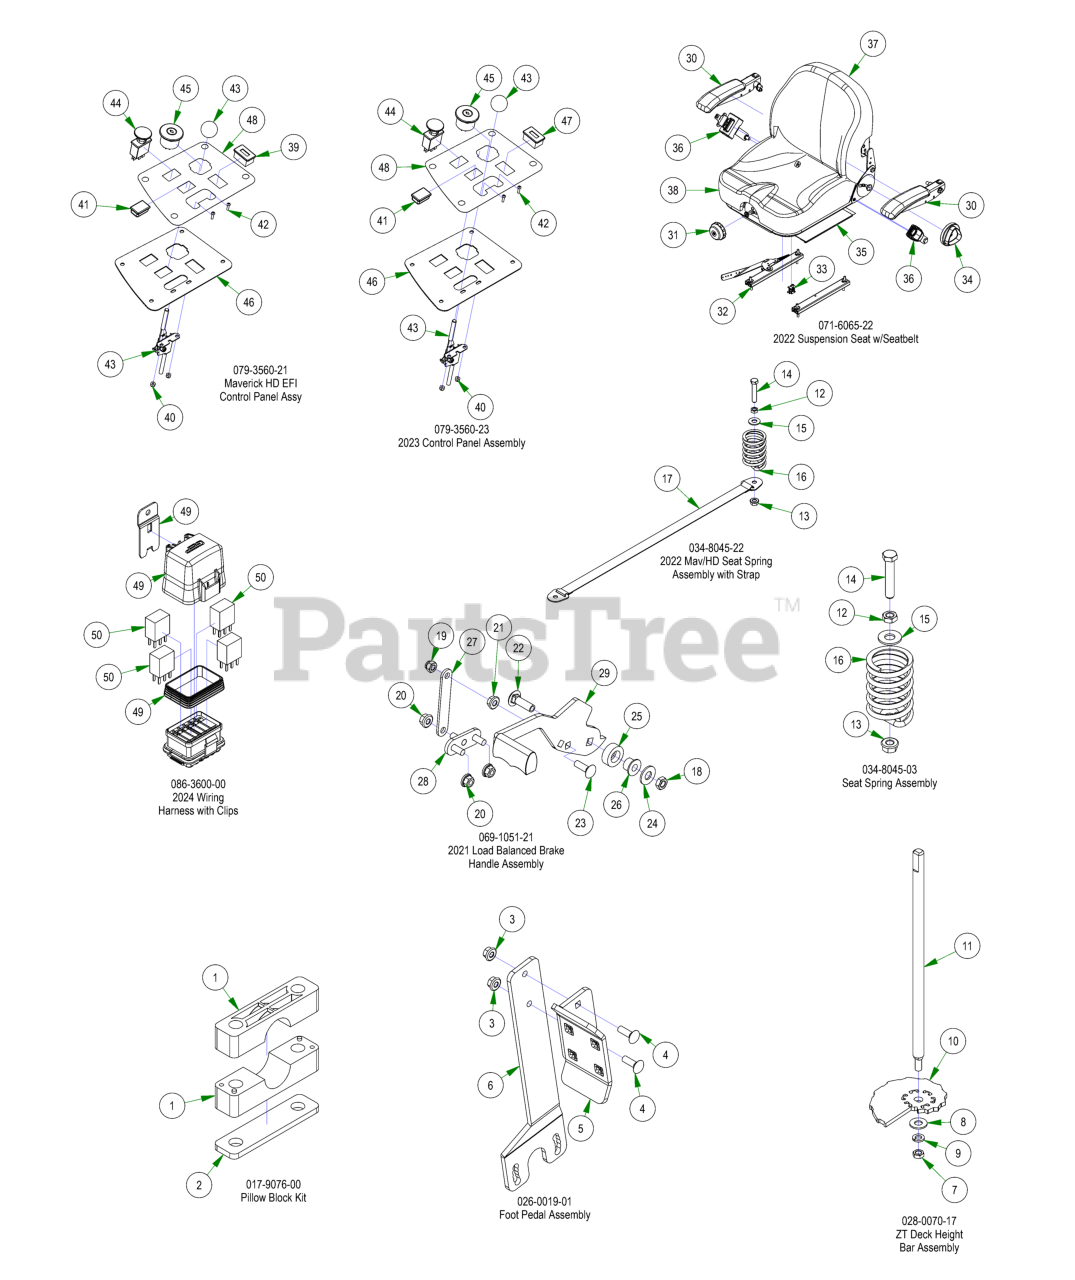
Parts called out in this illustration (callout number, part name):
1	Pillow Block MZ
2	Pillow Block Strap
3	5/16-18 NYLON INSERT FLANGE LOCKNUT ZINC
4	5/16-18 X 1 CARRIAGE BOLT (GR.8) ZINC
5	2017 MZ/ZT Shallow Foot Pedal
6	2017 MZ/ZT Deck Pedal Lever
7	3/8-24 HEX NUT ZINC YELLOW
8	3/8 FLAT WASHER USS (1" OD) ZINC
9	3/8 SPLIT LOCKWASHER ZINC
10	2017 MZ/ZT Cam Plate
11	2017 Deck Height Dial Rod ZT
12	3/8-16 Half Jam Nut
13	3/8-16 HEX SERRATED FLANGE NUT HARD/ZINC
14	3/8-16 X 2 HEX CAP SCREW (GR.5) ZINC
15	3/8 FLAT WASHER USS (1" OD) ZINC
16	Seat Spring
17	Seat Strap with Buckles
18	3/8-16 HEX JAM 2-WAY REVERSIBLE CENTER LOCKNUT ZINC
19	5/16-18 NYLON INSERT CAP LOCKNUT ZINC (BLK CAP)
20	5/16-18 NYLON INSERT FLANGE LOCKNUT ZINC
21	5/16-18 HEX SERRATED FLANGE NUT HARD/ZINC
22	3/8-16 X 1-1/4 CARRIAGE BOLT ZINC
23	5/16-18 X 1 CARRIAGE BOLT (GR.8) ZINC
24	3/8 FLAT WASHER USS (1" OD) ZINC
25	2015 Brake Lever Spacer
26	.377 ID X .625 OD X .500 HGT X .880 FLNG DIA X .060 FLNG THK
27	Brake Cable Extension Plate
28	Brake Load Balancer Lower Weldment
29	Load Balanced Brake Handle with Grip
30	Set of Armrests-SS Front Adj
31	Weight Adjust Indicator Knob Assy
32	4" Single Locking Track Kit
33	Delta Plunger Switch - N.O.
34	Recliner Adjustment Knob-New
35	Bellows w/Hardware
36	2" Retractable Belt Kit w/Spacers
37	Back Cover for I3M - Recl - Logos
38	Cushion Cover Kit for I3M-Logo
39	Tachometer
40	10-24 Nylon Insert Locknut Zinc Orange Nylon
41	Light Plug
42	10-24 X 5/8 BS Button Head Bolt
43	Throttle Lever Assembly
44	PTO Engager
45	Ignition Switch
46	2022 Maverick HD control panel
47	Tachometer
48	2023 MZ/Magnum/ZT/Maverick Control Panel Decal
49	Relay Block Cover Replacement Kit
